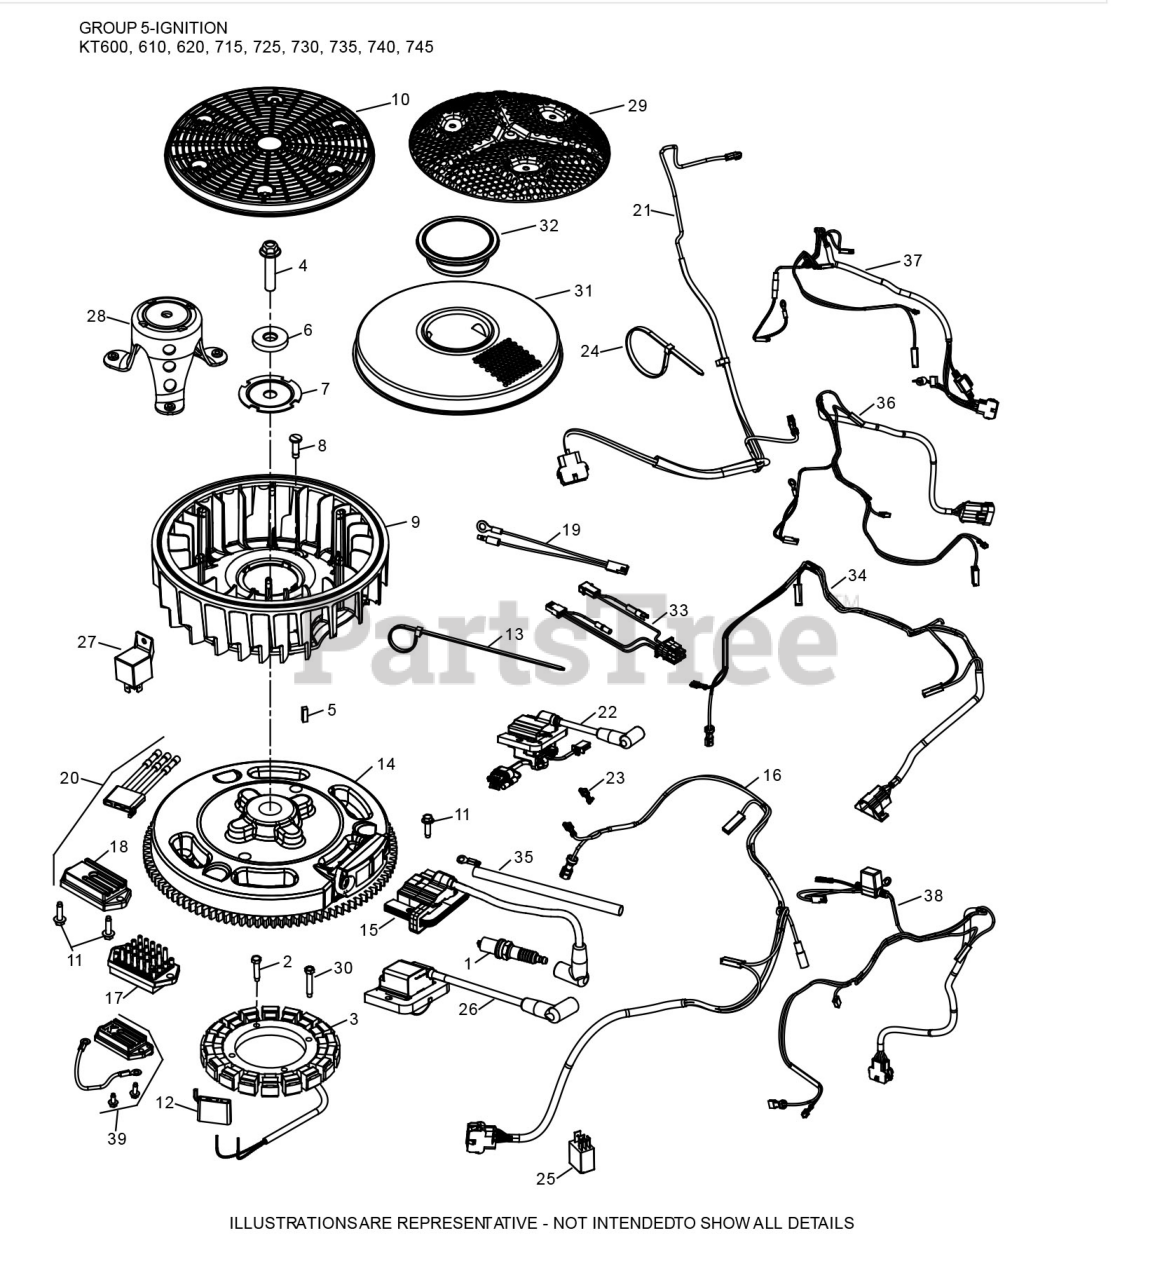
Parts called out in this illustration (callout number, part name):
1	SPARK PLUG RFI
2	THREAD FORMING SCREW
3	KIT-STATOR
4	HEX FLANGE BOLT
7	PLATE-FAN MOUNTING
11	THREAD FORMING SCREW
14	FLYWHEEL ASSEMBLY
16	WIRING HARNESS ASSEMBLY
18	REGULATOR RECTIFER 12/15A HALFWAVE
26	IGNITION MODULE
